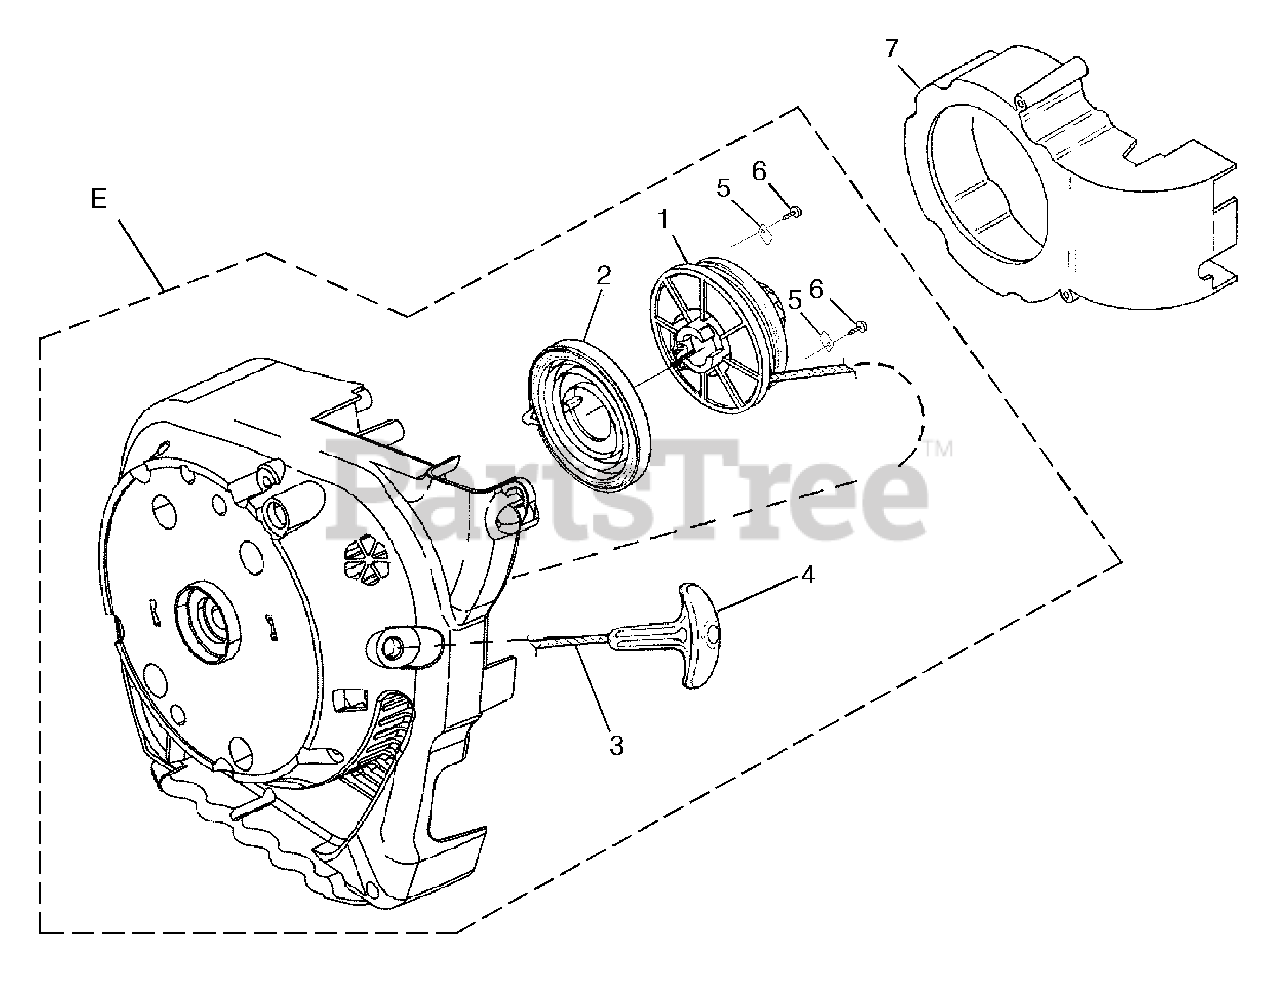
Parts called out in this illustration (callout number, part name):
1	Pulley, Starter
2	Spring & Container
3	Rope, Starter 42"
4	Grip, Starter (Black)
5	Bracket-Retaining
6	Screw-Plastite (#10-1/2")
7	Scroll
E	Starter (Svc)
